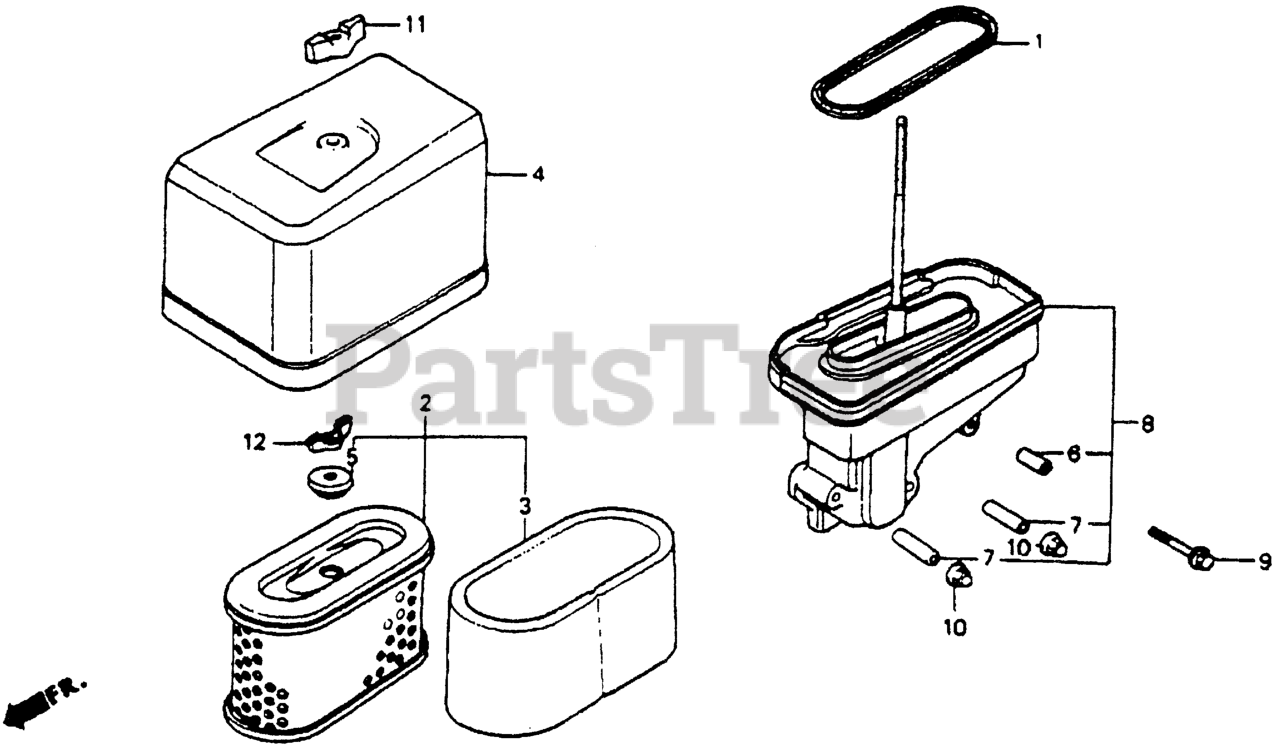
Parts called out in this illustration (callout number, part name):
1	GASKET, ELBOW
2	ELEMENT, AIR CLEANER (METAL BASE)
3	FILTER (OUTER)
4	COVER, AIR CLEANER (DUAL)
5	GROMMET, AIR CLEANER
6	COLLAR, AIR CLEANER Use up to Engine SN 1786084.
7	COLLAR, AIR CLEANER
8	ELBOW, AIR CLEANER
9	BOLT, FLANGE (6X35)
10	NUT, CAP (6MM)
11	WINGNUT (6MM)
12	WINGNUT, TOOL BOX SETTING
